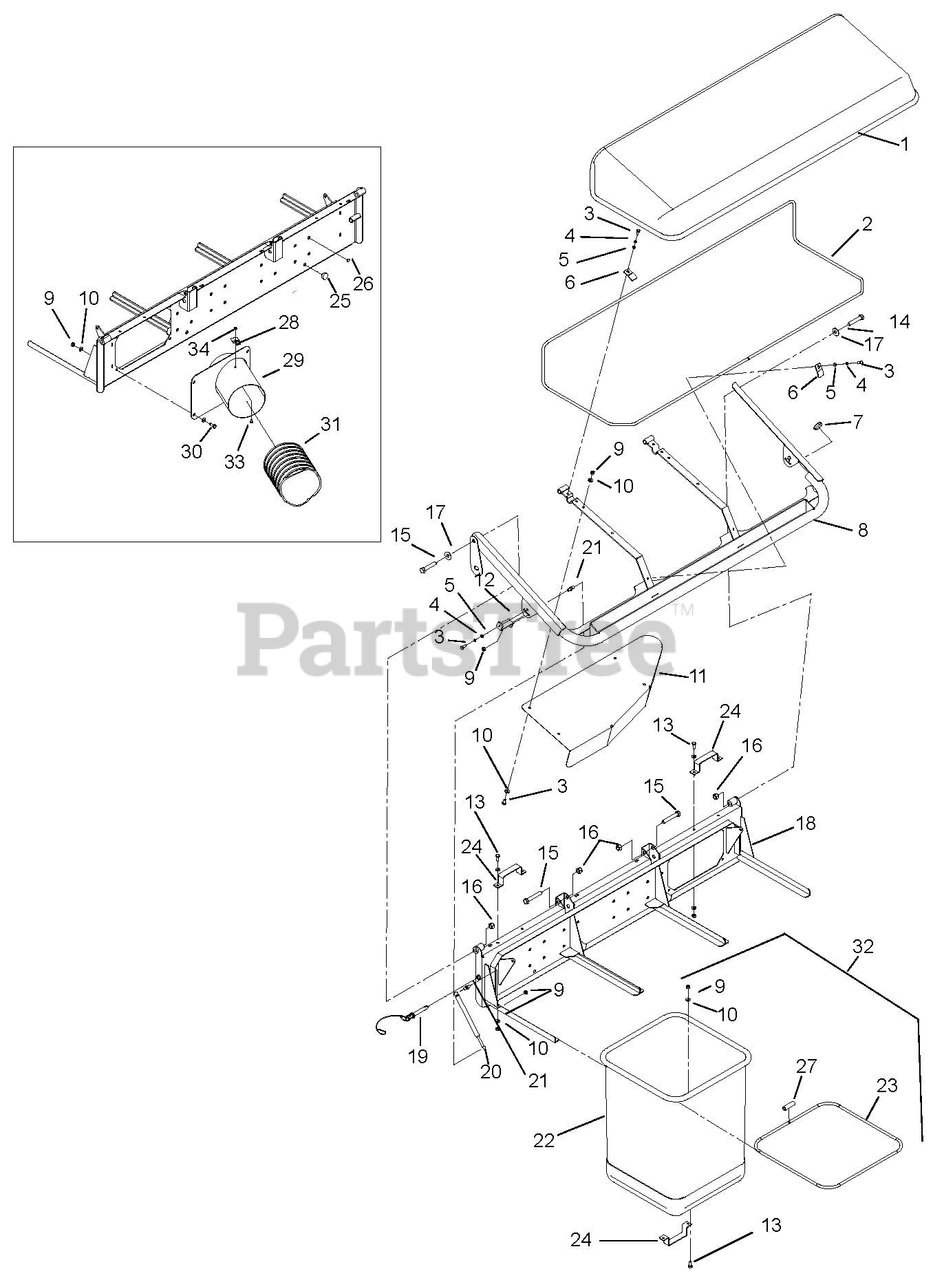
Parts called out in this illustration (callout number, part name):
1	3-Bag Fabric Cover W/J-Strip
2	Air Dome Frame .38 Rod
3	Bolt, Hex .25-20 x .75 Grade 5
4	Washer, Locking .25 x .062
5	Washer, Flat Steel .281 x .62 x .065
6	Bracket, Mount Single Hole
7	Hole Plug, Round
8	Cap Support – 3 Bag
9	Nut, .31-18 Nyloc Flange
10	Washer, Flat, Steel .344 x .688 x .065
11	3-Bag Deflector
12	Bracket, Gas Cylinder Mount
13	Bolt, Hex .31-18 x .75 Grade 5
14	Bolt, Hex .50-13 x 2.50 Grade 5
15	Bolt, Hex .50-13 x 3.00 Grade 5
16	Nut, Locking-Nylon .50-13
17	Washer, Flat-Steel .531 x 1.06 x .095 YWZC
18	3-Bag Support Mount
19	Detent Pin W/Lanyard 1/2 x 2.50
20	Gas Cylinder
21	Ball Stud
22	Cloth Bag
23	Grass Bag Frame
24	Bag Handle
25	Rubber Bumper
26	Hole Plug 7/16
27	Tube Connector
28	Thumb Latch, A-10 Quick Release
29	Inlet Adapter 200 Series
30	Bolt, Hex .31-18 x 1.00 Grade 5
31	Hose, Bagger 49"
32	Bag Assembly
33	Screw, Machine 10-24 x .50 Hex Washer Head
34	Nut, Locking Nylon 10-24 with Insert
